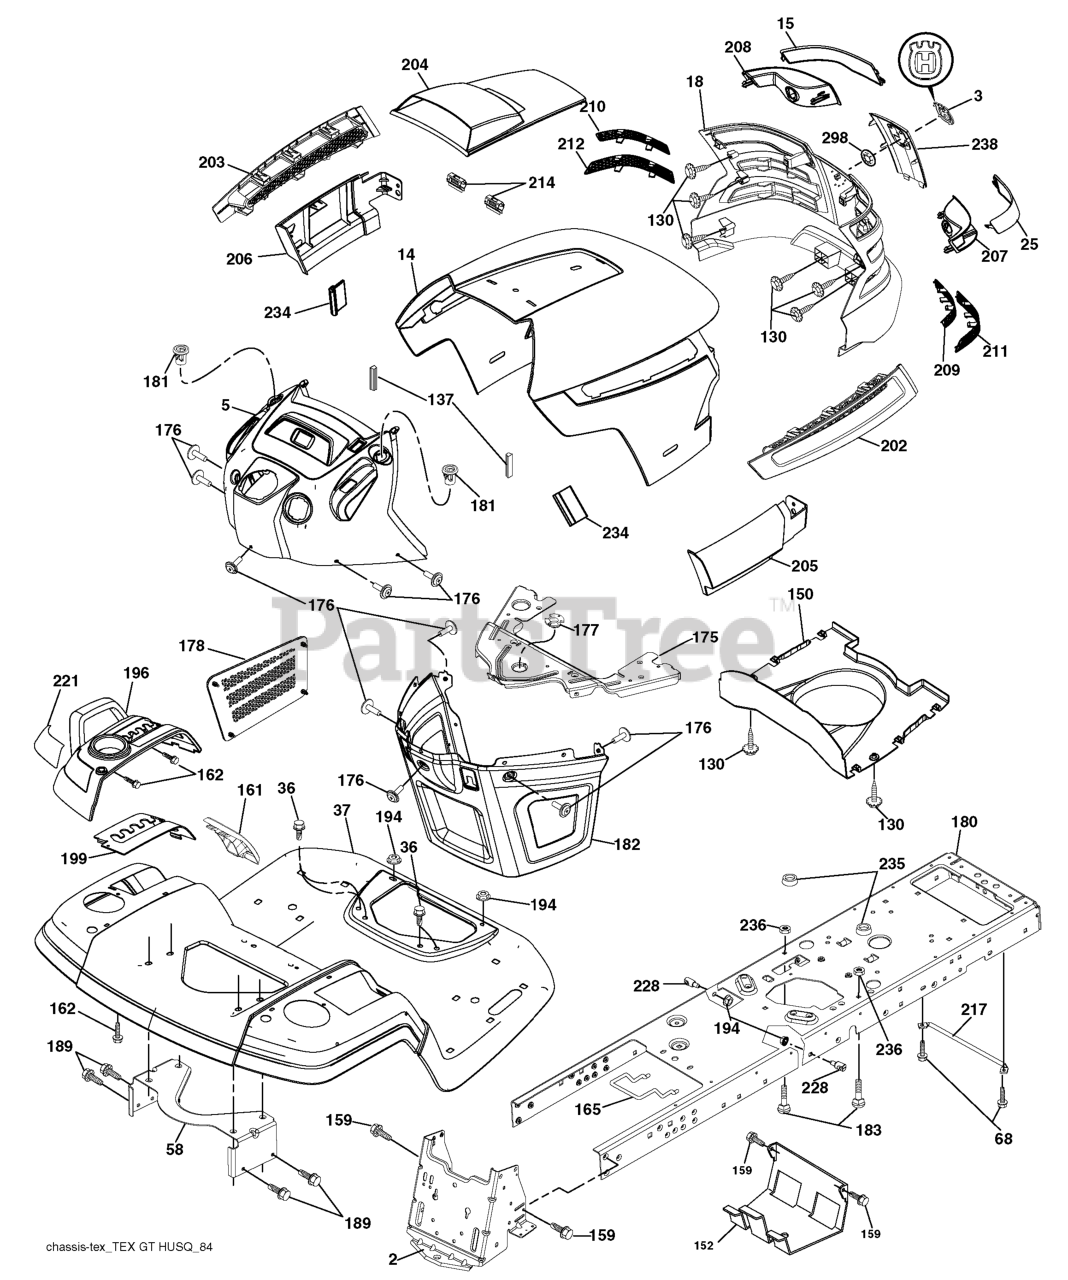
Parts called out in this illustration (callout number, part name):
2	DRAWBAR.STGT
3	RP LOGO
5	DASH.ASM.GTHUSQTX.RGS.ELECT.CK
14	HOOD
15	LENS.LH.TEX.GT.HUSQ.CL
18	GRILL.ASM.HUSQ.TG/CRD.W/TRIM
25	LENS.RH.TEX.GT.HUSQ.CL
36	SCREW 5/16"
37	FENDER.PNT.TX.GT.CH/FW.ORANGE
58	BRKT.SUPPORT.FNDR/TANK
68	Screw 5/16-18 x 1/2
130	SCREW.#10 X 0.750.BOS
137	BUMPER DASH
150	AIR.DUCT.HOOD.TEX.GT.HUSQ
152	SHIELD.BROWNING/DEBRIS
159	SCREW, 3/8-16X3/4
161	CONSOLE.FUEL.WINDOW.HU
162	SCREW.HI-LO.CONSOLE
165	SUPPORT.TANK.REAR.B/TE
175	PLATE.CROSSMEMBER.HUSQ
176	SCREW.#10-24X5/8.RN.QU
177	BUSHING, STEERING
178	CARGO.ASM.NET.TXGT.W/C
180	CHASSIS.STAMPING.LT/GT
181	BUSHING.MNT.FEND.CRGO.
182	DASH.LOWER.COMMON.12V.ADAPTOR
183	BOLT.5/16-18X1-1/4 FULL THD
189	SCREW
194	NUT LOCK HEX FLANGE 5/16-18
196	CONSOLE.ASM.DCKLFT.W/RF.HQ.DLR
199	PLATE.DECK.LIFT.HUSQVARNA.GT
202	VENT.SIDE.HOOD.HUSQ.RH.GREY
203	VENT.SIDE.HOOD.HUSQ.LH.GRAY
204	HOOD VENT
205	SKIRT.HOOD.SIDE.HUSQ.RH.GREY
206	SKIRT.HOOD.SIDE.HUSQ.LH.GREY
207	BEZEL.RH.TEX.GT.HUSQ
208	BEZEL.LH.TEX.GT.HUSQ
209	INSERT.HEX.GRILL.HUSQ.GREY
210	INSERT.HEX.GRILL.HUSQ.
211	INSERT.HEX.GRILL.HUSQ.
212	INSERT.HEX.GRILL.HUSQ.
214	CLIP.RETAINER.TINNER.
217	ROD.PIVOT.HOOD
221	REFLECTOR.LH.TEX GT HU
228	STUD.FASTNER.W/ANTI-ROTATE
234	BUMPER.HOOD.TEX.HUSQVARNA
235	SPACER FENDER
236	NUT.CENTERLOCK.5/16-
238	TRIM.HUSQ.TG/CRD.SERVICE
298	NUT PUSH M
